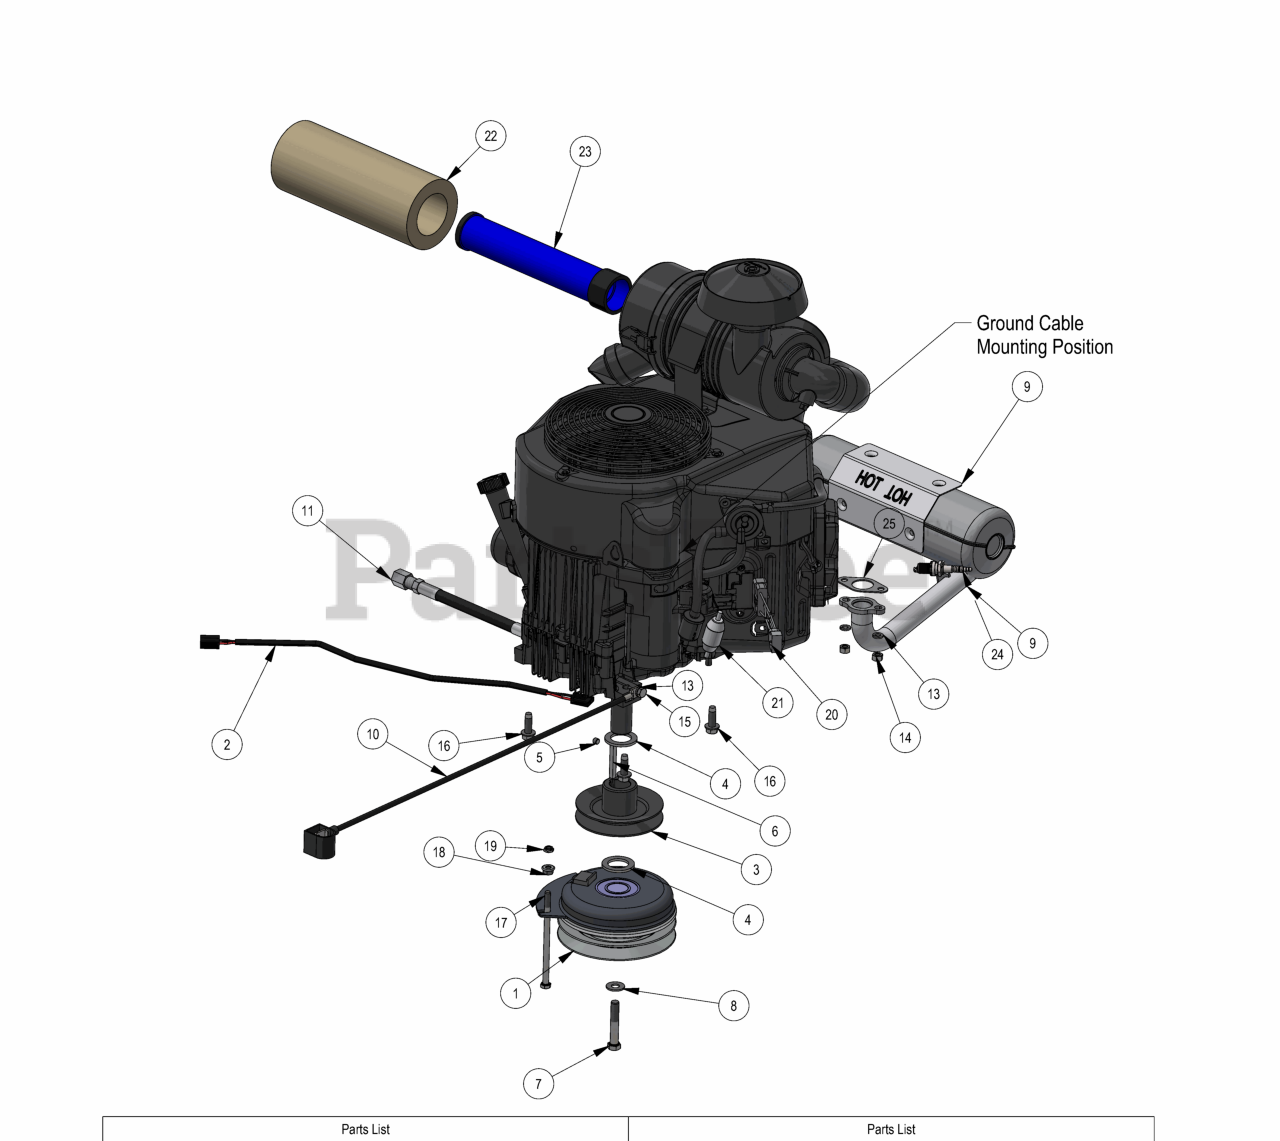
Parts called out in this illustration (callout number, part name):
1	Clutch Assembly
2	Clutch Pigtail
3	4 3/4 Motor Pulley
4	1.140 ID X 1.750 OD X .132 THICK FLAT WASHER PLAIN
5	5/16-24 X 1/4 SOCKET SET SCREW (CUP PT) PLAIN
6	1/4 X 2 SQ MACHINERY KEY 1018 STL PLAIN
7	7/16-20 X 2-1/2 HEX CAP SCREW (GR.8) ZINC YELLOW
8	3/8 FLAT WASHER USS (1" OD) ZINC
9	Exhaust-Stand On-FX691V Kawasaki
10	24 inch Black Cable – MZ/ZT
11	Oil drain Hose
12	Exhaust Gasket
13	5/16 SPLIT LOCKWASHER ZINC
14	M8-1.25 DIN 934 HEX NUT (CL.8) ZINC
15	M8-1.25 X 20MM DIN 933 HEX TAP BOLT (CL 8.8) ZINC
16	3/8-16 X 1-1/8HEX WASHER UNSLOT SERRATED
17	5/16-18 X 5-1/2 HEX CAP SCREW (GR.5) ZINC
18	5/16" Flange Nut
19	5/16-18 NYLON INSERT JAM LOCKNUT ZINC
20	2019 Harness Adaptor-Gen2 FX-ALL
21	Universal Inline Fuel Filter
22	Canister Air Filter- Outer
23	Canister Air Filter- Inner
24	Spark Plug - Kawasaki
25	Exhaust Gasket
26	Oil Filter
27	FX691 Kawasaki-2016 Compact Outlaw
